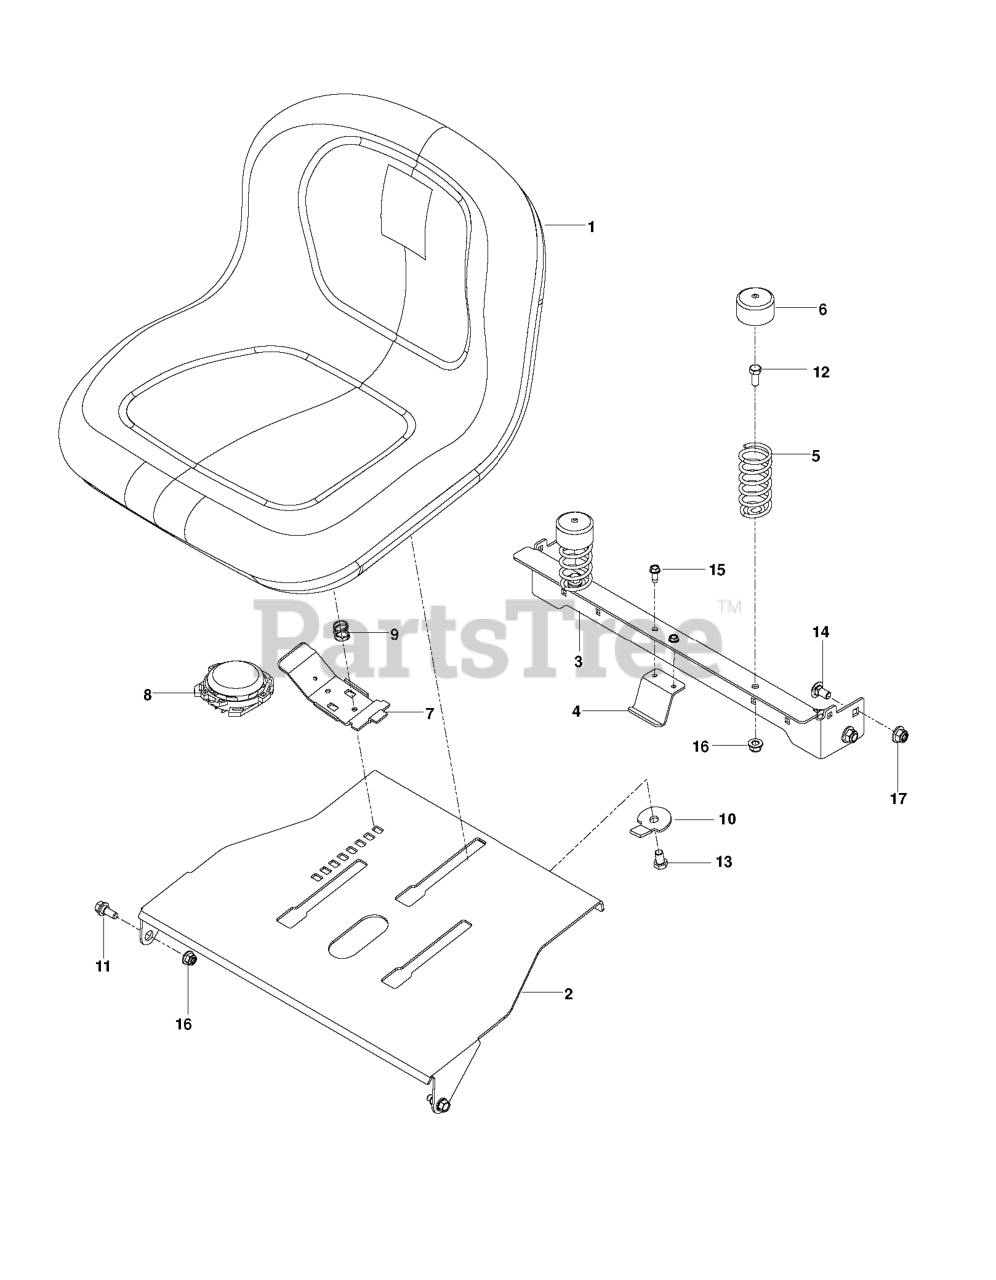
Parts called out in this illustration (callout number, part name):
1	SEAT.TH150.MS498.GRY.HUSQ.TEX
2	PLATE, SEAT, ORG
3	SUPPORT, REAR SEAT, ORG
4	HOLDING DEVICE, FUEL TANK, BLK
5	SEAT SPRING
6	SPRING CAP
7	HANDLE.SLIDE.SEAT.TEX.BLACK
8	SWITCH, SEAT N/C
9	SPRING.LATCH.SEAT.TEX
10	STOP, SEAT, BLACK
11	BOLT, SHOULDER
12	HCS 5/16C X 3/4
13	HCS 3/8-16 X 5/8 GR 5 ZD
14	RHSNB 3/8-16 X 3/4 GR5 ZD
15	SCREW 1/4 X 5/8
16	5/16-18 NYLOC FLANGE NUT
17	NUT 3/8-16 HEX FLG NYLOC ZD
